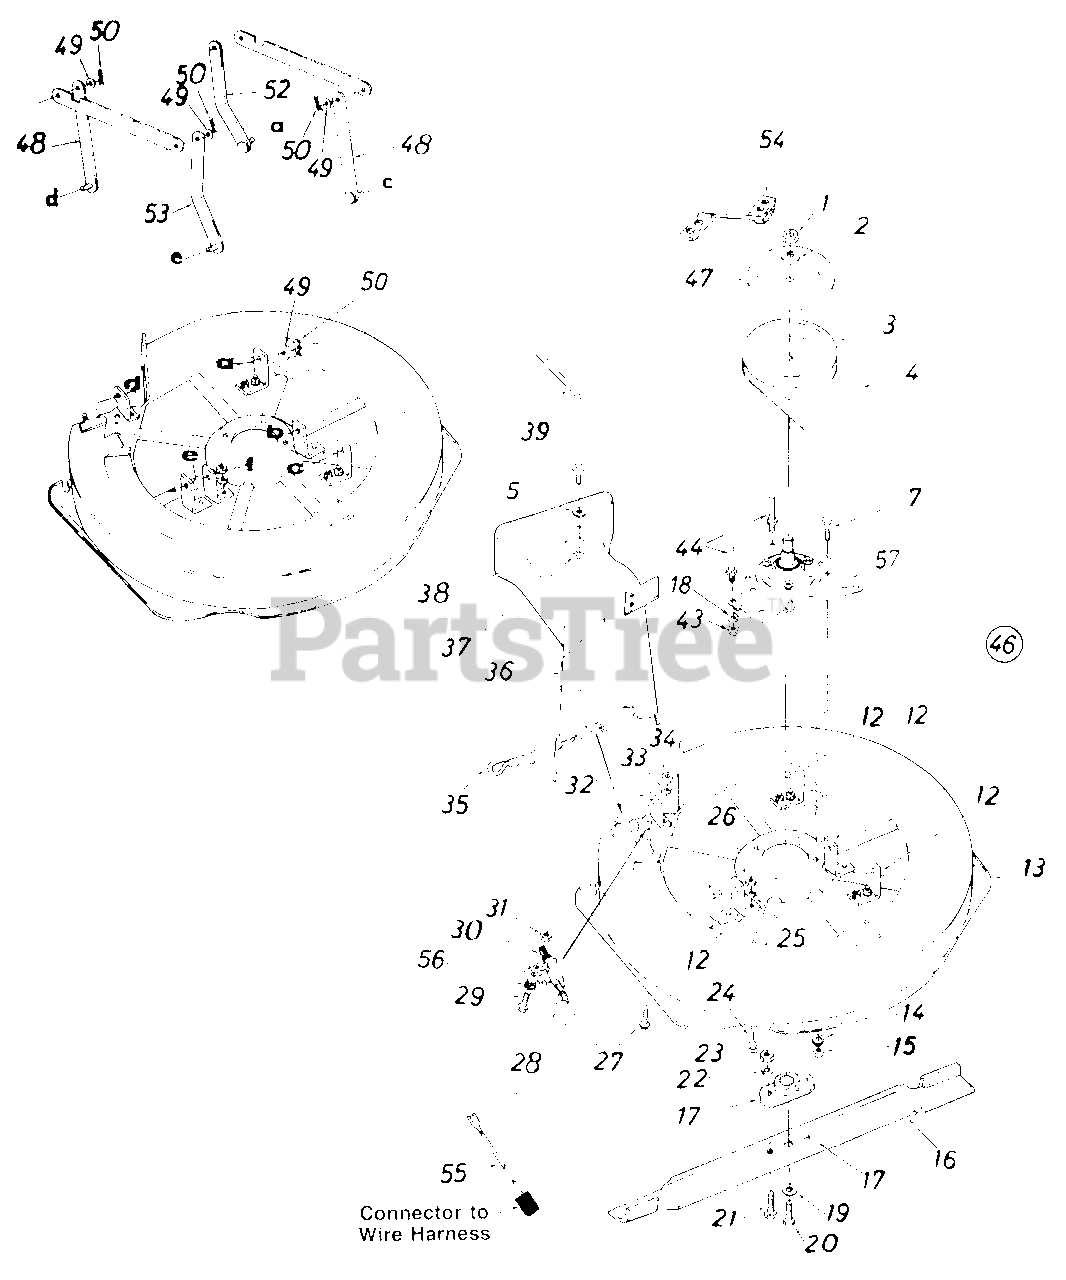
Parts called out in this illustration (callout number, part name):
1	Hex Jam Nut 5/8-18 Thd.
2	Bell-Wash. .630" I.D. x 1.25"
5	Fl-Wash. .344" I.D. x 1.12" 0. D.
7	Hex Bolt 5/16-18 x .75" Lg.*
12	Hanger Bracket
15	Hex Nut 5/16-18 Thd.*
16	30" High Lift Blade-R.H.
17	Blade Adapter
18	L-Wash. 3/8" I.D.
19	Bell-Wash. .39" I.D. x 1.38" O.D.
20	Hex Bolt 3/8-24 x 1.00" Lg.
21	Hex Bolt 5/16-24 x 1.00" Lg.
22	L-Wash. 5/16" I.D.*
23	Hex Nut 5/16-24 Thd.*
24	Hex Sems Bolt 5/16-18 x .62" Lg.*
25	L-Wash. 5/16" I.D.*
26	Hex Nut 5/16-18 Thd.*
27	Truss Mach. Scr. 5/16-18 x .75" Lg.*
28	Electrical Wire
29	Hex Bolt 1/4-20 x .50" Lg.
30	Safety Switch
31	Hex Nut 1/4-20 Thd.
32	Angle Hanger Brkt.
33	L-Wash. 5/16" I.D.
34	Hex Nut 5/16-18 Thd.
35	Internal Cotter Pin
36	R.D. Chute Deflector
37	Hex L-Nut 5/16-18 Thd.
38	L-Wash. .32" I.D. x .62" O.D.
39	90ø Rod 5/16-18 Thd.
43	Hex Jam Nut 3/8-16 Thd.
44	Stud 3/8-16 x 3.0" Lg.
46	30" R.D. Deck Ass'y. Comp.
47	Brake Disc
48	Link Deck Hanger Ass'y.
49	Fl-Wash. .53" I.D. x .93 O.D.
50	Inter. Cotter Pin .50" Dia.
54	Blade Brake Ass y.
55	Wire Lead
56	L-Wash. 1/4" I.D.
57	Blade Spindle Ass'y. Comp.
